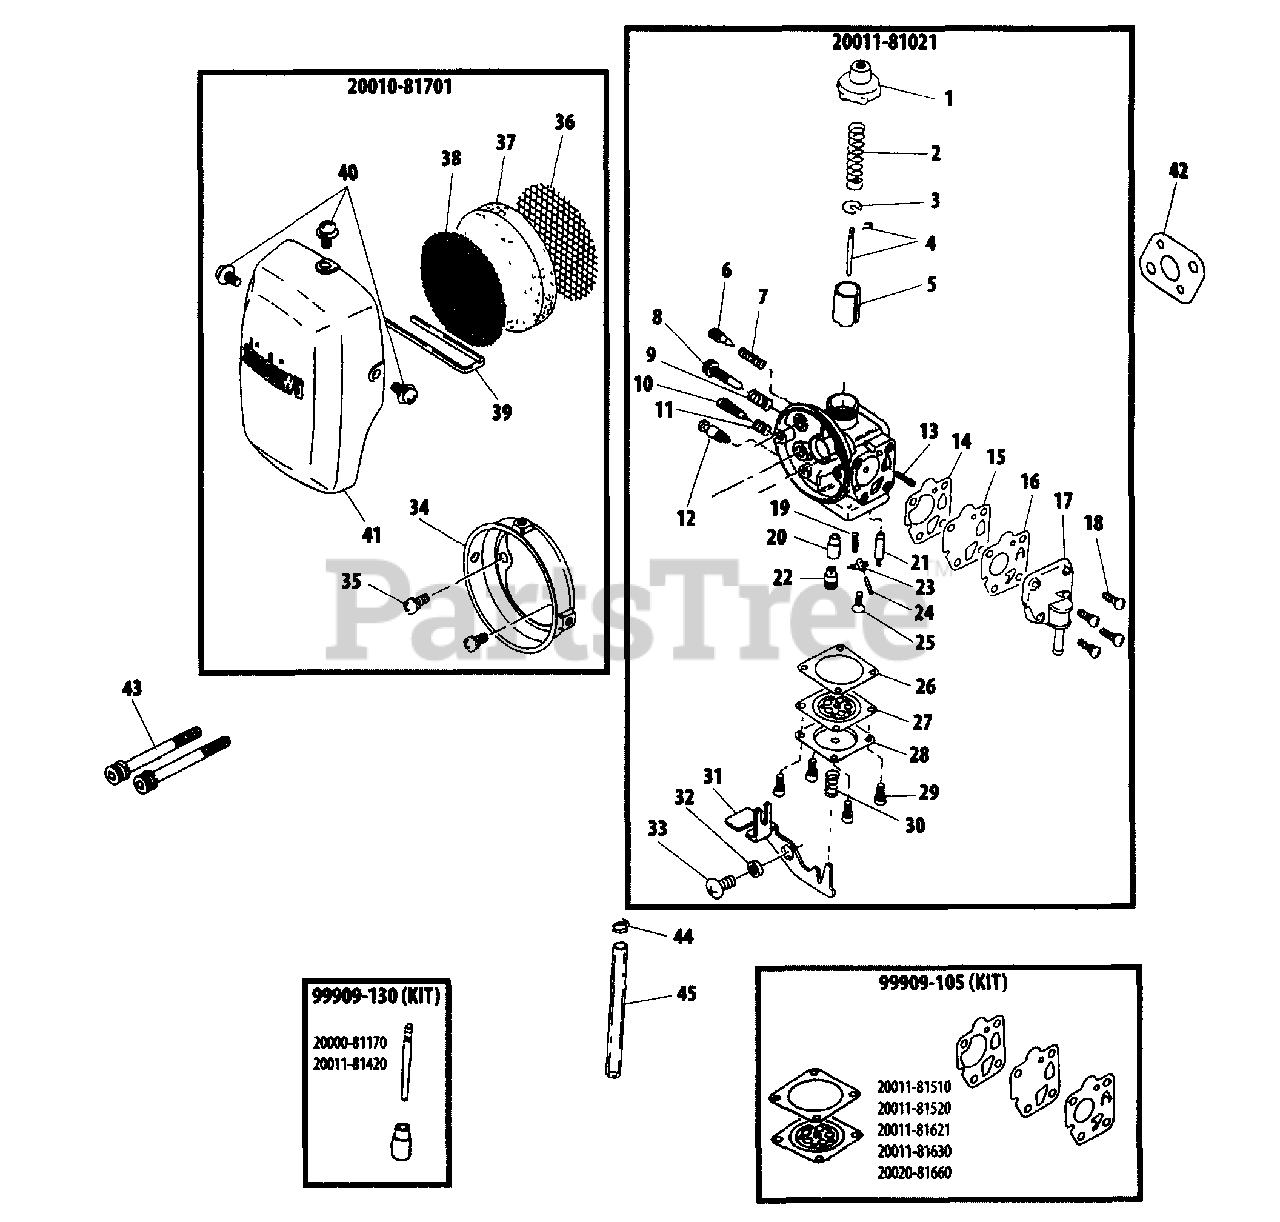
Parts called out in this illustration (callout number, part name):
1	CAP, THROTTLE
2	SPRING
3	WASHER, SPRING SUPPORT
4	NEEDLE, JET
5	VALVE, THROTTLE
6	SCREW, SLOW AIR
7	SPRING
8	SCREW, IDLE ADJUST
9	SPRING
10	SCREW, MAIN ADJUST
11	SPRING
12	VALVE, OVERFLOW
13	SPRING, COIL
14	GASKET, DIAPHRAGM
15	DIAPHRAGM, METERING
16	VALVE, PUMP
17	BODY, PUMP
18	SCREW
19	SPRING
20	HOLDER, MAIN JET
21	VALVE, INLET NEEDLE
22	JET, MAIN
23	LEVER, METERING
24	PIN, METERING LEVER
25	SCREW M3×8
26	GASKET
27	DIAPHRAGM, METERING
28	COVER, DIAPHRAGM
29	SCREW M3×8
30	SPRING
31	LEVER, TICKLER
32	COLLAR
33	SCREW
34	CASE, AIR FILTER
35	SCREW
36	SCREEN, REAR
37	FILTER, AIR
38	SCREEN - FRONT
39	CLIP, FILTER RETAINING
40	SCREW 4
41	COVER, AIR FILTER
42	GASKET
43	BOLT M5×50
44	CLIP
45	PIPE
20010-81701	AIR FILTER ASSY
20011-81021	CARBURETOR
99909-105	DIAPHRAGM/GASKET KIT
99909-130	NEEDLE/JET KIT
